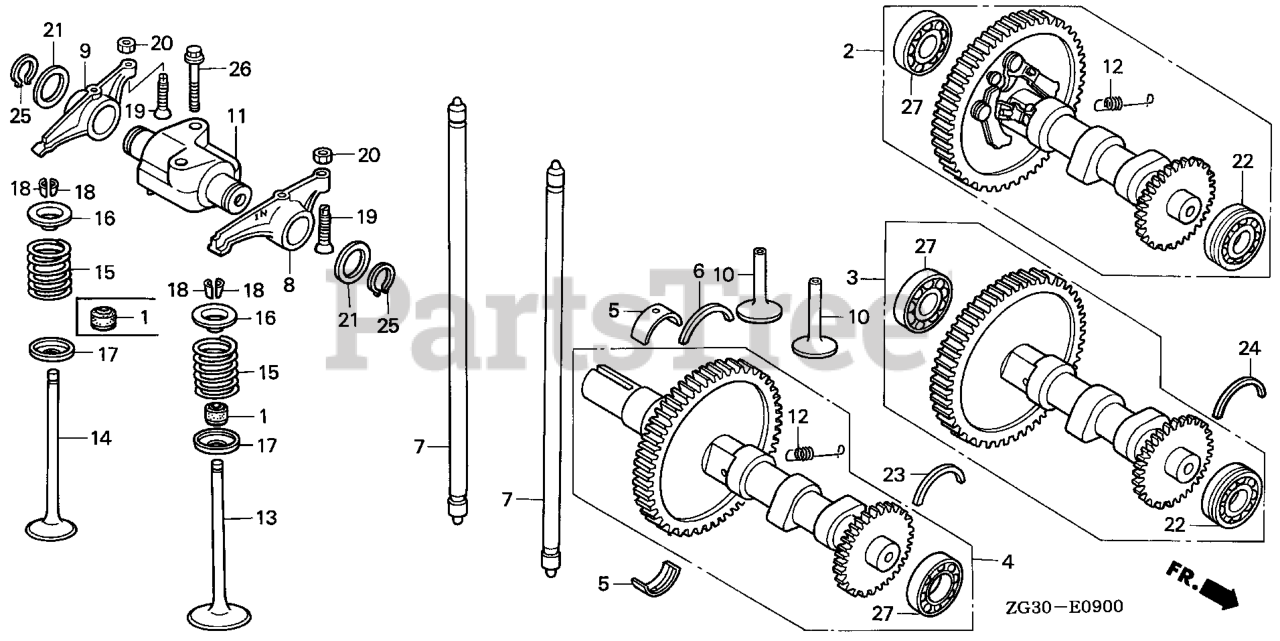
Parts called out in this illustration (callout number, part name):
1	SEAL A, VALVE STEM (ARAI)
2	CAMSHAFT ASSY. (USA)
7	ROD, PUSH
8	ARM, IN. VALVE ROCKER
9	ARM, EX. VALVE ROCKER
10	LIFTER, VALVE
11	SHAFT, ROCKER ARM
12	SPRING, WEIGHT RETURN
13	VALVE, IN.
14	VALVE, EX.
15	SPRING, VALVE
16	RETAINER, VALVE SPRING
17	SEAT, VALVE SPRING
18	COTTER, VALVE
19	SCREW, TAPPET ADJ.
20	NUT, TAPPET ADJ.
21	WASHER, THRUST (16MM)
22	BEARING A, SPECIAL BALL (6204) (NTN CORP.)
24	SET-RING (470)
25	CIRCLIP (OUTER) (16MM)
26	BOLT, FLANGE (6X35)
27	BEARING, RADIAL BALL (6204)
